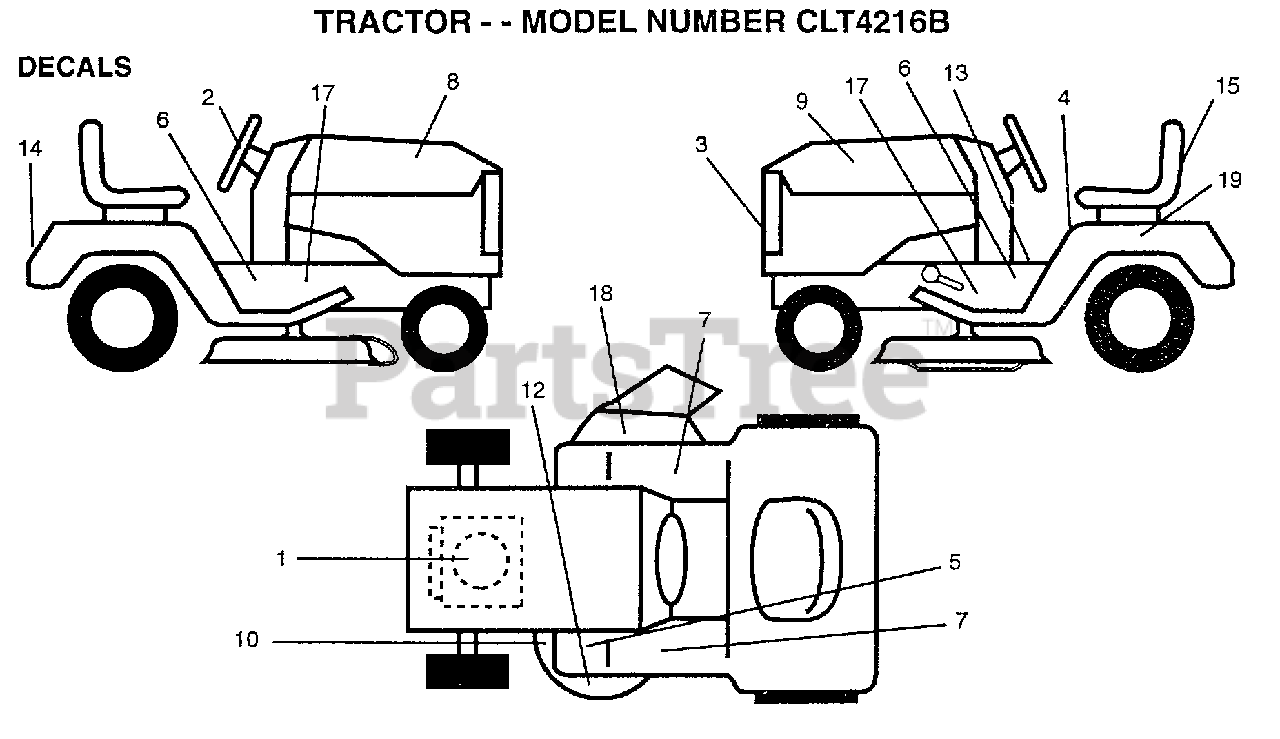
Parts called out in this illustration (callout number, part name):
1	DECAL, HP ENGINE
2	DECAL INST WHL
3	DECAL LOGO GRILLE
4	DECAL CAUT FEND
5	DECAL CLUT/BRAKE
6	DECAL CHASSIS KGR
7	FOOTREST PAD
8	DECAL HOOD RH
9	DECAL HOOD RH
10	DECAL
12	DECAL.DECK.KGRO.
13	DECAL.SADDLE.INST
14	DECAL.FEND.KGRO
17	DECAL.CHAS.KGRO
18	DECAL DANGER CT/F
19	DECAL.BTRY.DANGER
